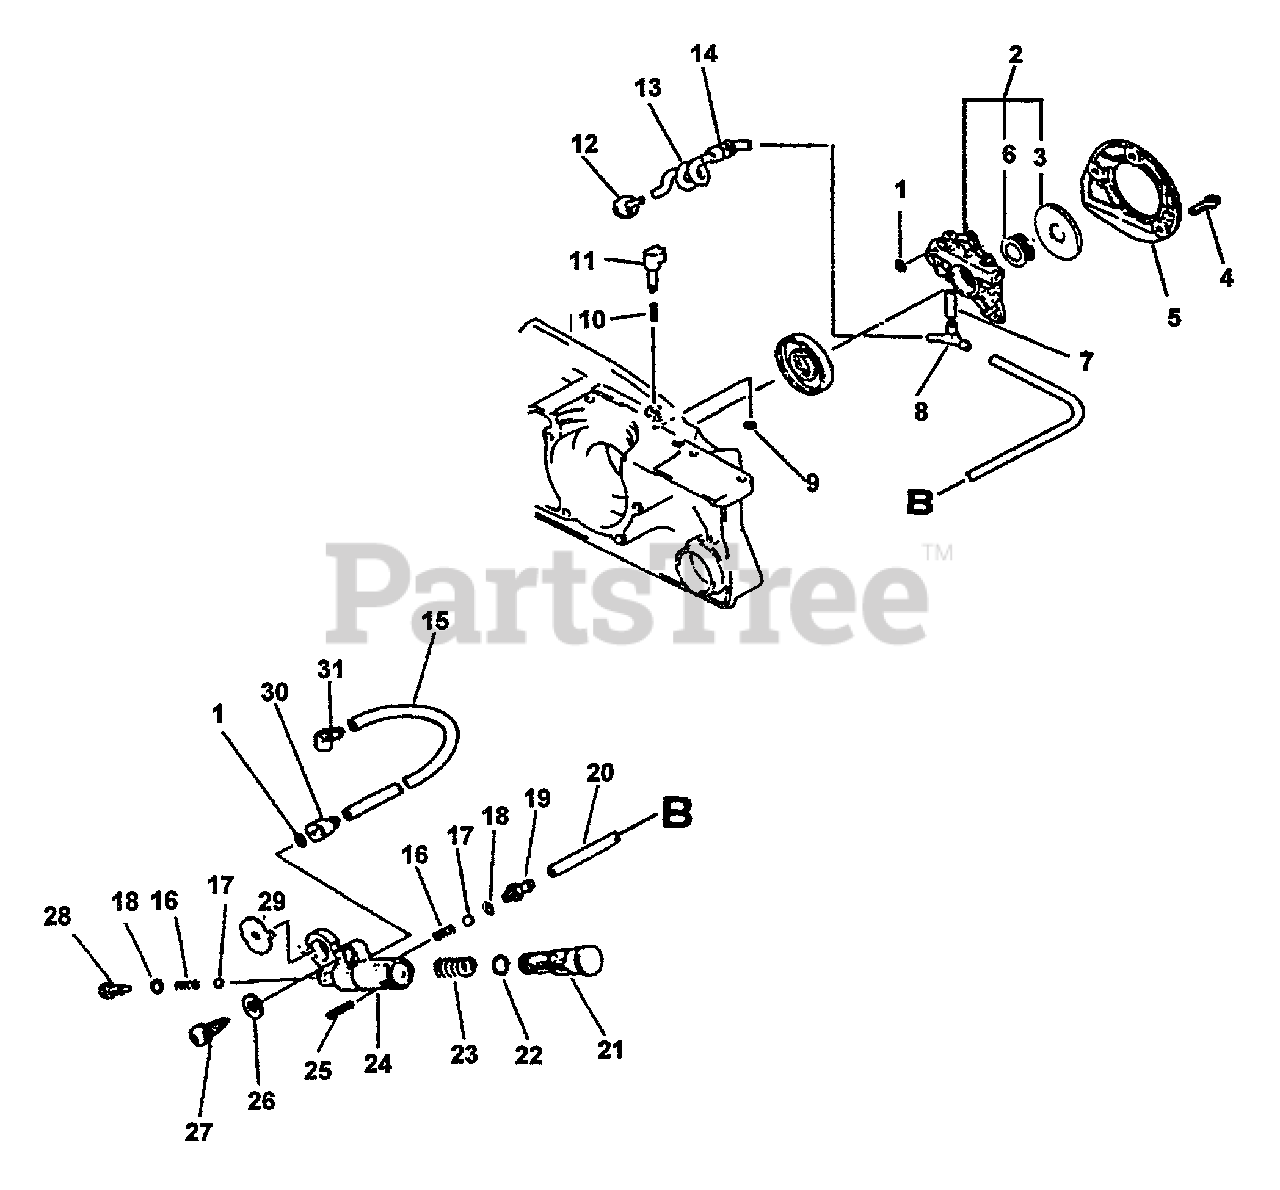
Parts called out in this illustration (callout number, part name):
1	O-RING - 3
2	AUTO-OILER ASSY
3	WASHER - 12
4	SCREW - 4X12
5	COVER, OIL PUMP
6	GEAR - WORM
7	CONNECTOR, PIPE
8	PIPE - 3X6X20 -- BLACK
9	RING, RETAINING - 3
11	DIAL, AUTO-OILER
12	FILTER, OIL
13	PIPE - OIL
15	PIPE, OIL - 3X6X125
16	SPRING, VALVE
17	VALVE, BALL
20	PIPE - OIL
21	PISTON, OIL PUMP
22	O-RING - 7
24	BODY, OIL PUMP
25	PIN - SPRING -- 2X16
26	WASHER - 5
27	SCREW - 5X20
28	ADAPTER, OIL PUMP
29	BRACKET, OIL PUMP
30	CONNECTOR, PIPE
31	CONNECTOR, PIPE
